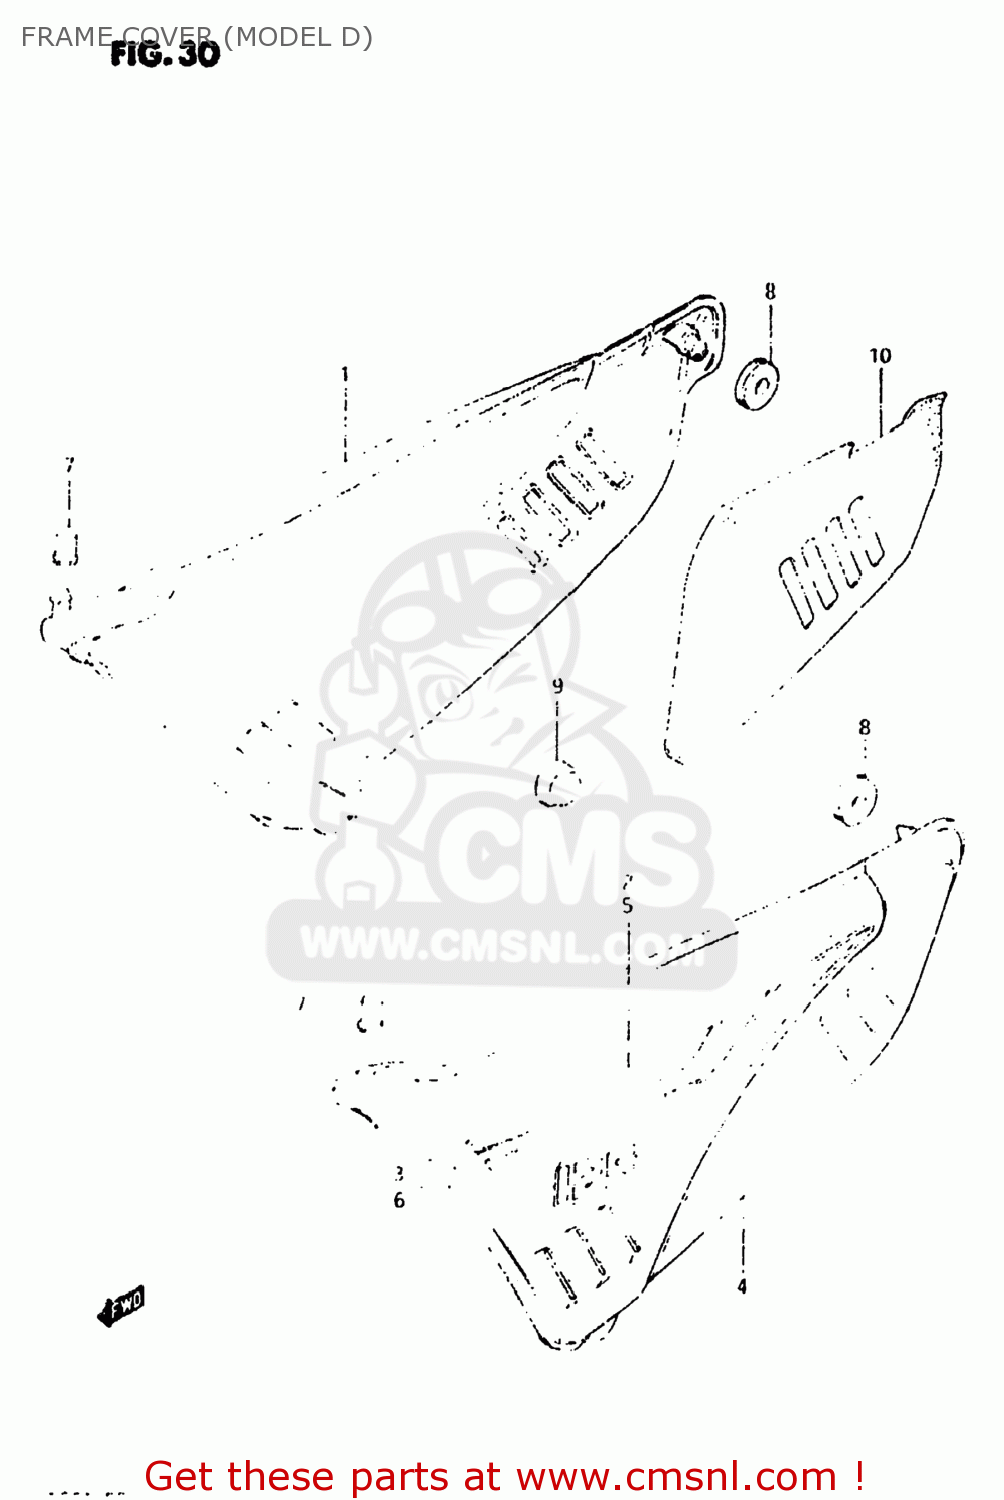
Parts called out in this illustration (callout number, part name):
1	COVER,FRAME,RIGHT
2	TAPE SET,FRAME COVER,RIGHT
3	EMBLEM
4	COVER,FRAME,LEFT
5	TAPE SET,FRAME COVER
6	EMBLEM
7	CUSHION
8	CUSHION
9	HEAT SHIELD,FRAME COVER
10	CUSHION
